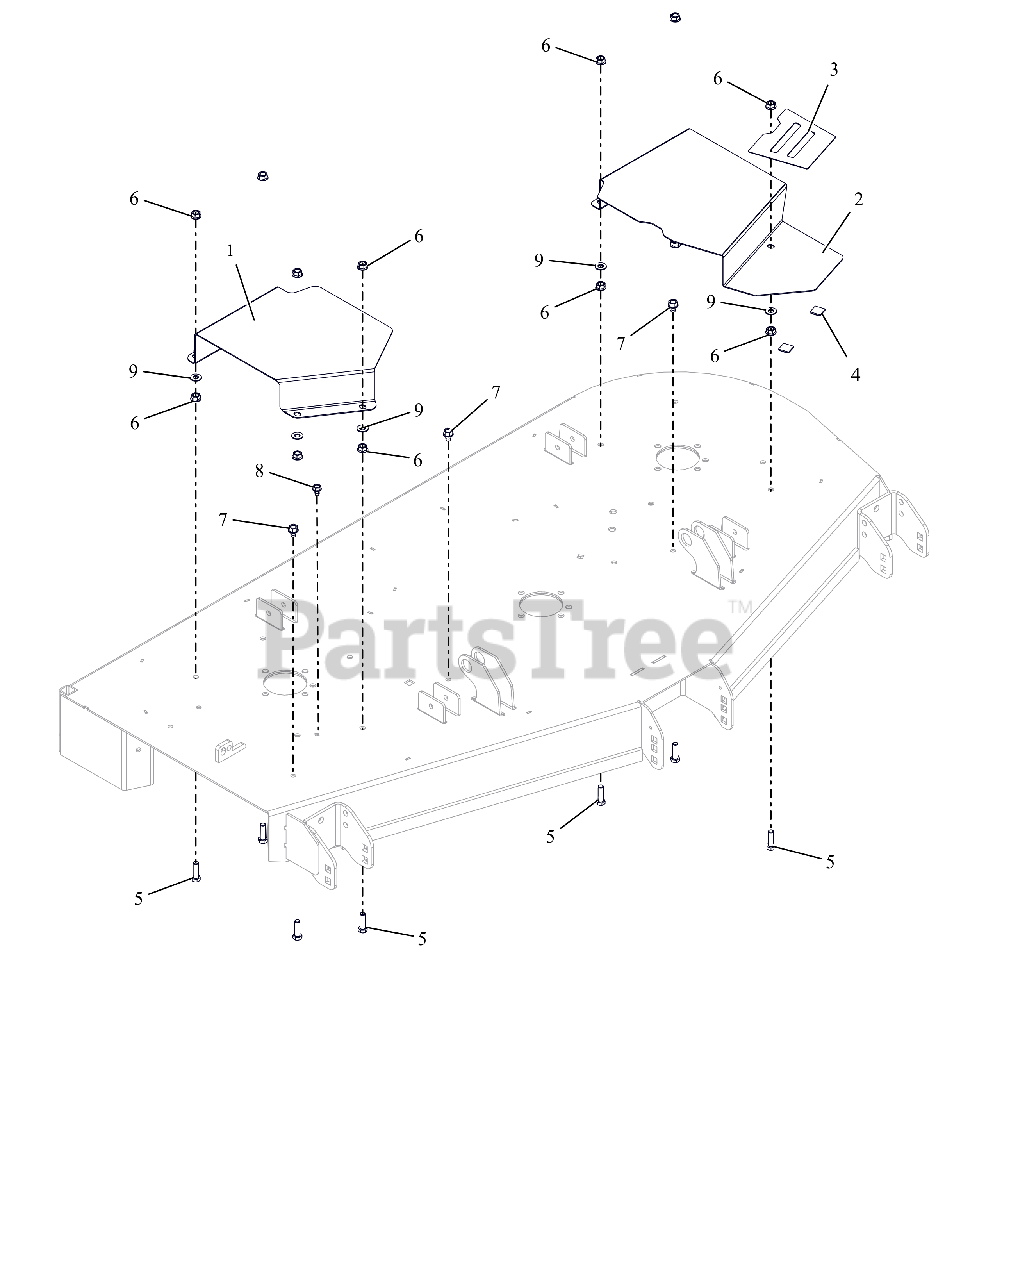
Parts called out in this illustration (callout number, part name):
1	COVER, BELT 52" & 60" RIGHT
2	COVER, BELT 60" LEFT
3	GRIP TAPE 52-60 BELT COVER
5	@BLT-HEX .38-16X1.25 GR5 YWZC
6	@NUT-SPNLK-FLG .375-16 YWZC
7	@SCR-TAP .38-16X.50 HWH TR YWZ
8	@SCR-TAP .31-18X.50 HWH TR YWZ
9	@WSHR-FL-STL.406X.812X.065 YWZ
